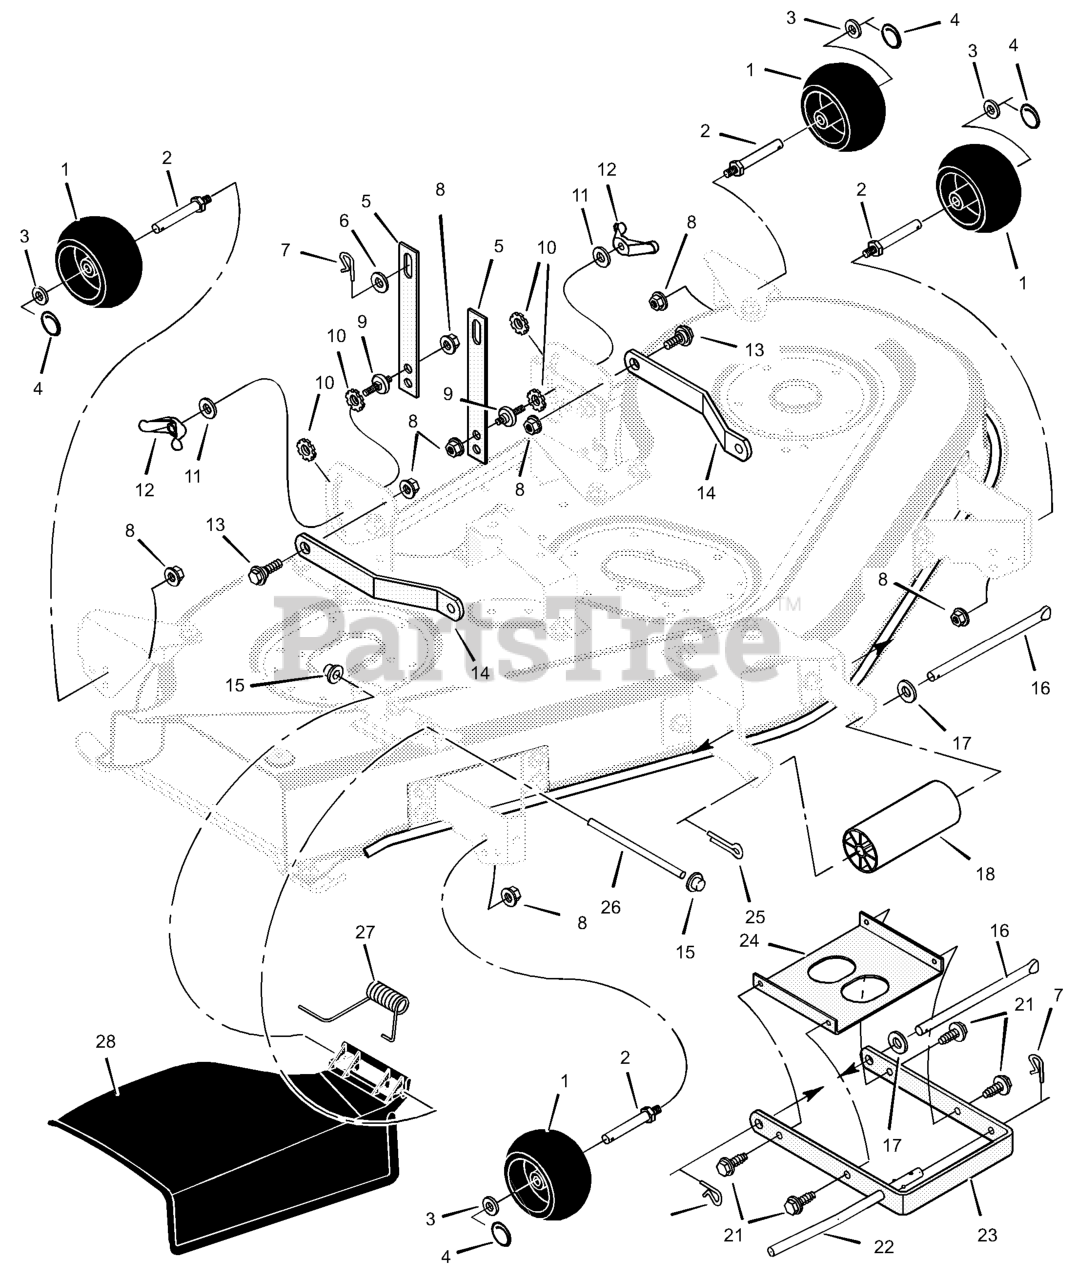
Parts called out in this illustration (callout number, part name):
1	Wheel, Gage
2	BOLT, Gauge Wheel
4	Pin, Hair
5	Link, Lift
7	Pin, Hair
8	Locknut
9	Pin, Hanger
12	Wingnut
13	Bolt, Shoulder
14	Bracket, Rear Suspension
15	Cap, Push
16	Rod, Deck Suspension
22	Rod, Hanger
23	Bracket, Front Suspension
24	Stiffener
25	Pin, Cotter
26	Rod, Deflector
27	Spring, Torsion
28	Deflector, Chute
